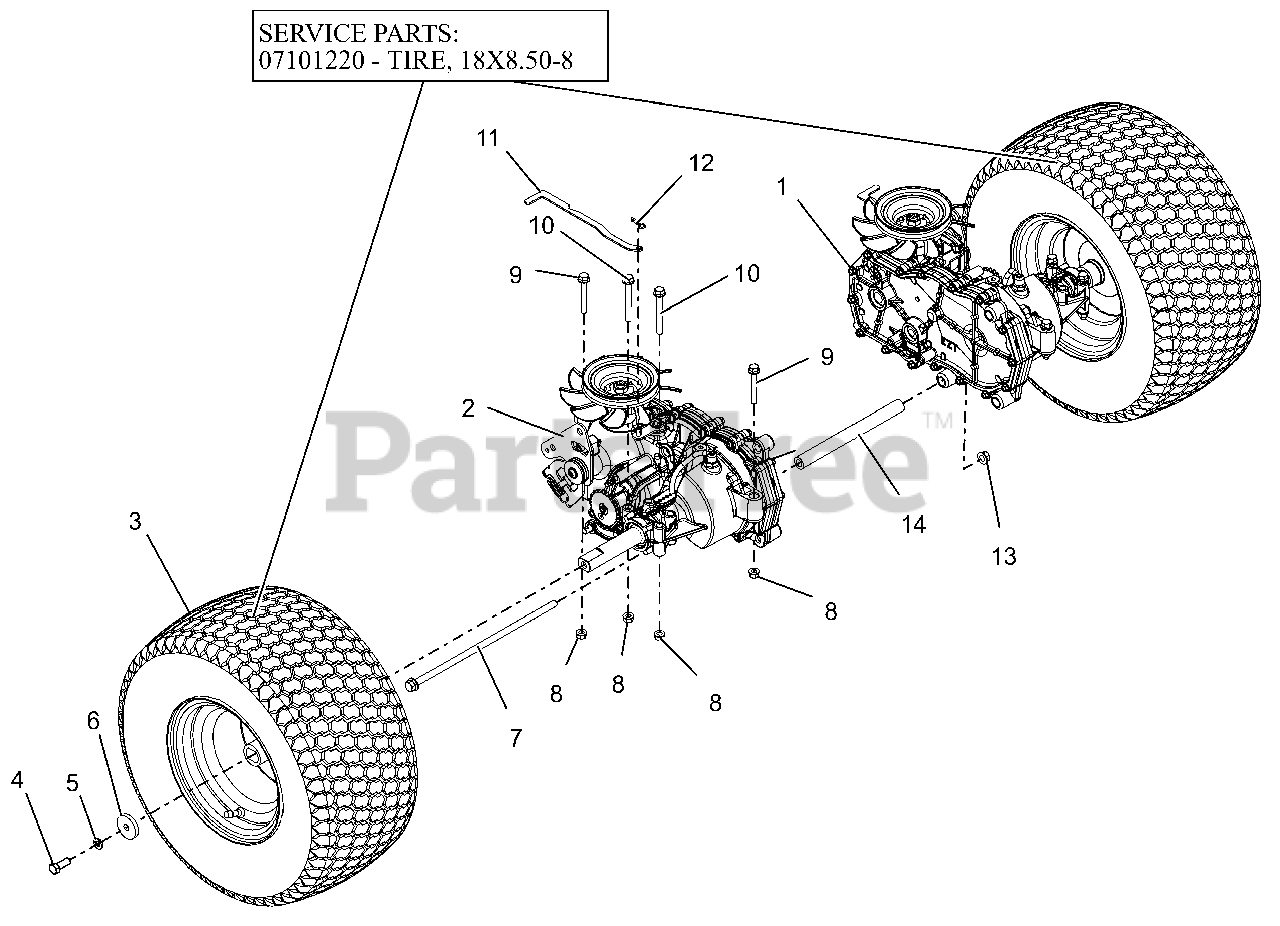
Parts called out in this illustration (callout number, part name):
1	TRANSAXLE, LH EZT D-SHFT SHORT
2	TRANSAXLE, RH EZT D-SHFT SHORT
3	ASM, WHL/TIRE 18X8.50-8 DHUB
3	TIRE, 18X8.50-8
3	TUBE 18X9.50-8
4	BLT, HEX .38-16X1.00 G8ZCCEP30
5	WSHR,LK-REG .375X.094 ZCC
6	WSHR, FLT .406X1.50X.245 ZCC
7	BLT, HEX-FLG 0.375-16X11.5 GR5 ZC120
8	NUT,LK-CTR-FLG .31-18 GF ZCC
9	BLT,HEX-FLG .31-18X2.25 G5 ZCC
10	BLT,HEX-FLG .31-18X2.75 G5 ZCC
11	BRKT, DUMP VALVE
12	PIN, HAIR #213 .08X1.19 ZCC
13	NUT-LK-CTR-FLG .375-16 GF ZCC
14	SPCR, TRANSAXLE .438 ID X .750 OD X 8.18 (BLACK)
